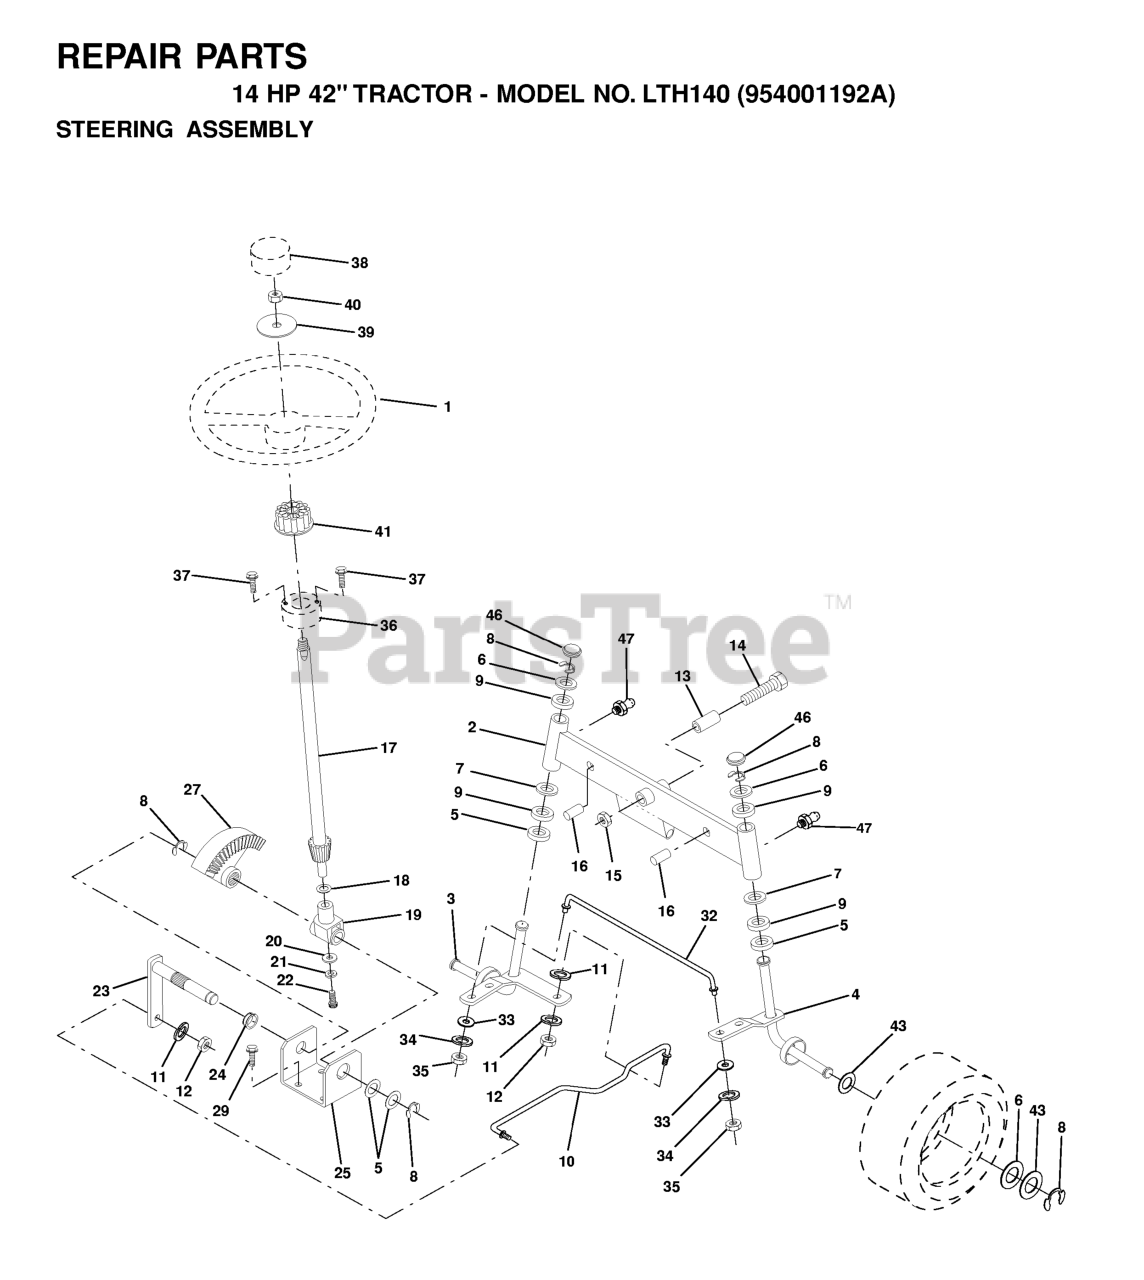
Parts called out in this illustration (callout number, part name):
1	STEERING WHEEL
3	SPINDLE LH
4	SPINDLE RH
5	THRUST WASHER
9	BRNG T
10	LINK.DRAG.SOL.BALL JT.20.064
11	WASHER, LOCK 3/8
12	NUT
13	BEARING
14	Bolt, Hex Head 5/8-11 x 3-1/2
15	NUT-LOC,FLANGE LT
17	STEERING SHAFT
18	THRUST WASHER
19	SHAFT,SUPPORT
20	WASHER
21	LOCKWASHER
22	SCREW,SPECIAL
23	SHAFT PITMAN
24	NYLINER T (7283A)
25	BRKT,STEERING
27	GEAR.SECTOR
29	SCREW
32	TIE ROD
33	WASHER M
34	WASHER.LOCK.HVY.HLCL.SPR.5/16
35	LOCKNUT
36	BUSHING LT
37	SCREW LT
38	INSERT,STR WHEEL
40	NUT.HEX.1/2-20
41	ADAPTER LT
46	CAP.SPINDLE.BLACK
47	ZERK M
